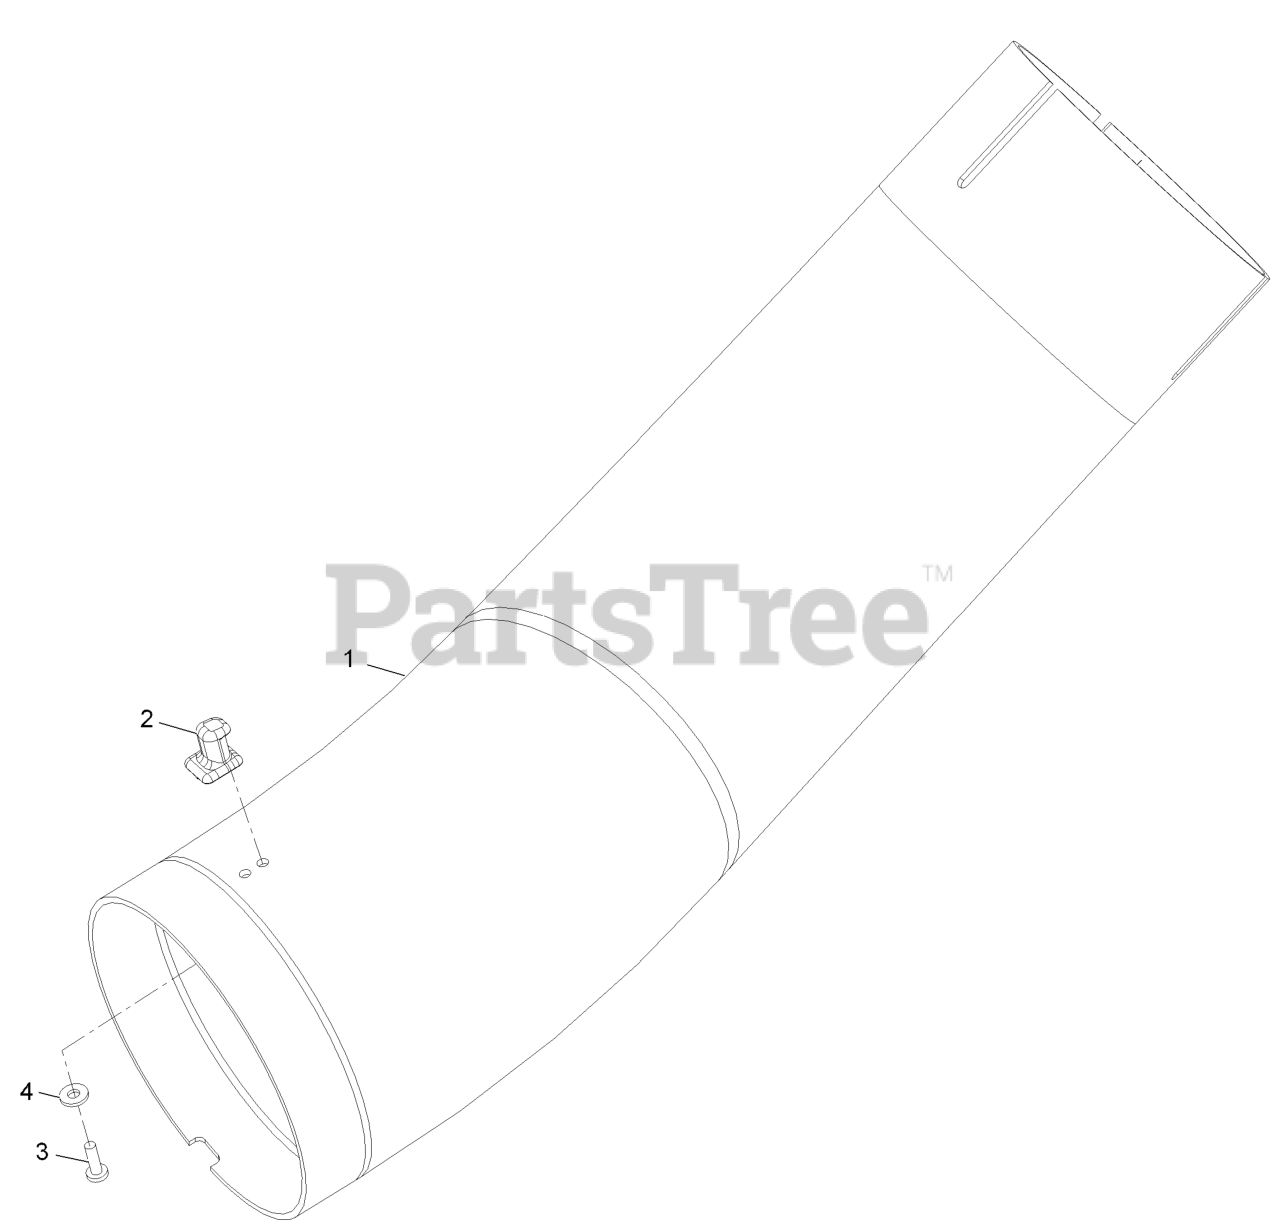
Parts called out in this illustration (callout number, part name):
1	Tube,Lower Short
2	LATCH-KEEPER
3	SCREW-PPH
4	WASHER-FLAT
